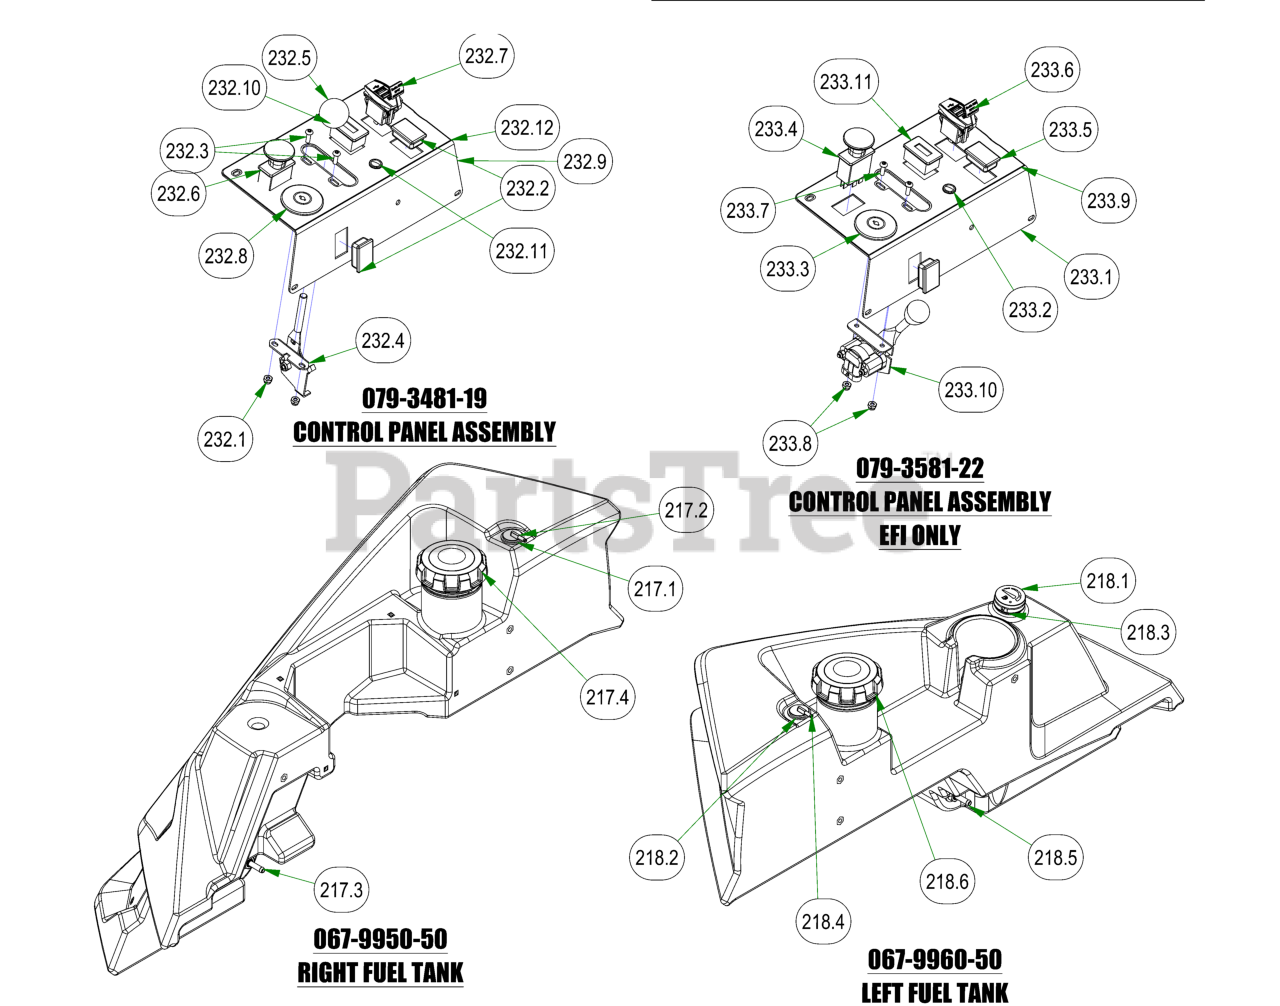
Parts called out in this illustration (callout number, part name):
217	2019 Right Rebel, Rogue, Renagade Fuel Tank (GAS)
217.1	Roll Over Valve Grommet
217.2	Rollover Valve
217.3	Fuel Pick-up
218	2019 Left Rebel, Rogue, Renegade Fuel Tank (GAS)
218.1	Fuel Gauge with Grommet
218.2	Roll Over Valve Grommet
218.3	Fuel Gauge Grommet
218.4	Rollover Valve
218.5	Fuel Pick-up
232	Rebel/Rogue Control Panel Assy
232.1	10-24 NYLON INSERT LOCKNUT ZINC
232.2	Light Plug
232.3	10-24 X 5/8 BUTTON SOCKET CAP SCREW 18-8 STAINLESS STEEL
232.4	Universal Throttle Head - 2012
232.5	Throttle Knob
232.6	PTO Switch
232.8	Ignition Switch
232.9	2022 Rebel Control Panel
232.10	Tachometer
232.12	2022 Rebel/Rogue Control Panel Decal
233	Rebel/Rogue Control Panel Assy-Drive by Wire
233.1	2022 Rebel Control Panel
233.3	Ignition Switch
233.4	PTO Switch
233.5	Light Plug
233.7	10-24 X 5/8 BUTTON SOCKET CAP SCREW 18-8 STAINLESS STEEL
233.8	10-24 NYLON INSERT LOCKNUT ZINC
233.9	2022 Rebel/Rogue Control Panel Decal
233.10	Kawasaki \ Kohler Drive By Wire
233.11	Tachometer
